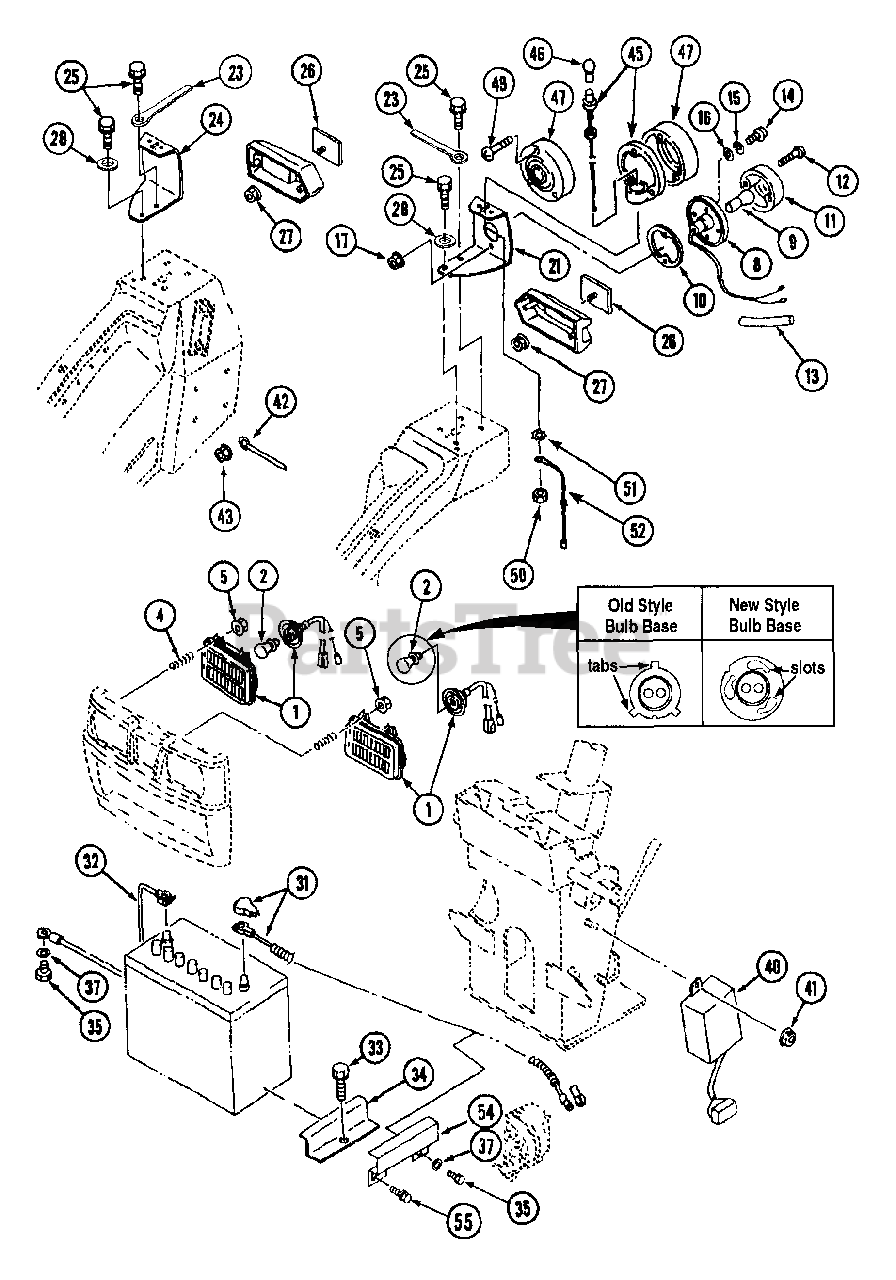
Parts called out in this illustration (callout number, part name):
1	Lamp, Head
8	Socket
15	Washer, Spring
21	Bracket, Lamp L.H.
24	Bracket, Lamp R.H.
32	Cord, Battery
34	Clamp, Battery
45	Body Ass'y.
46	Bulb
51	Washer, Tooth
